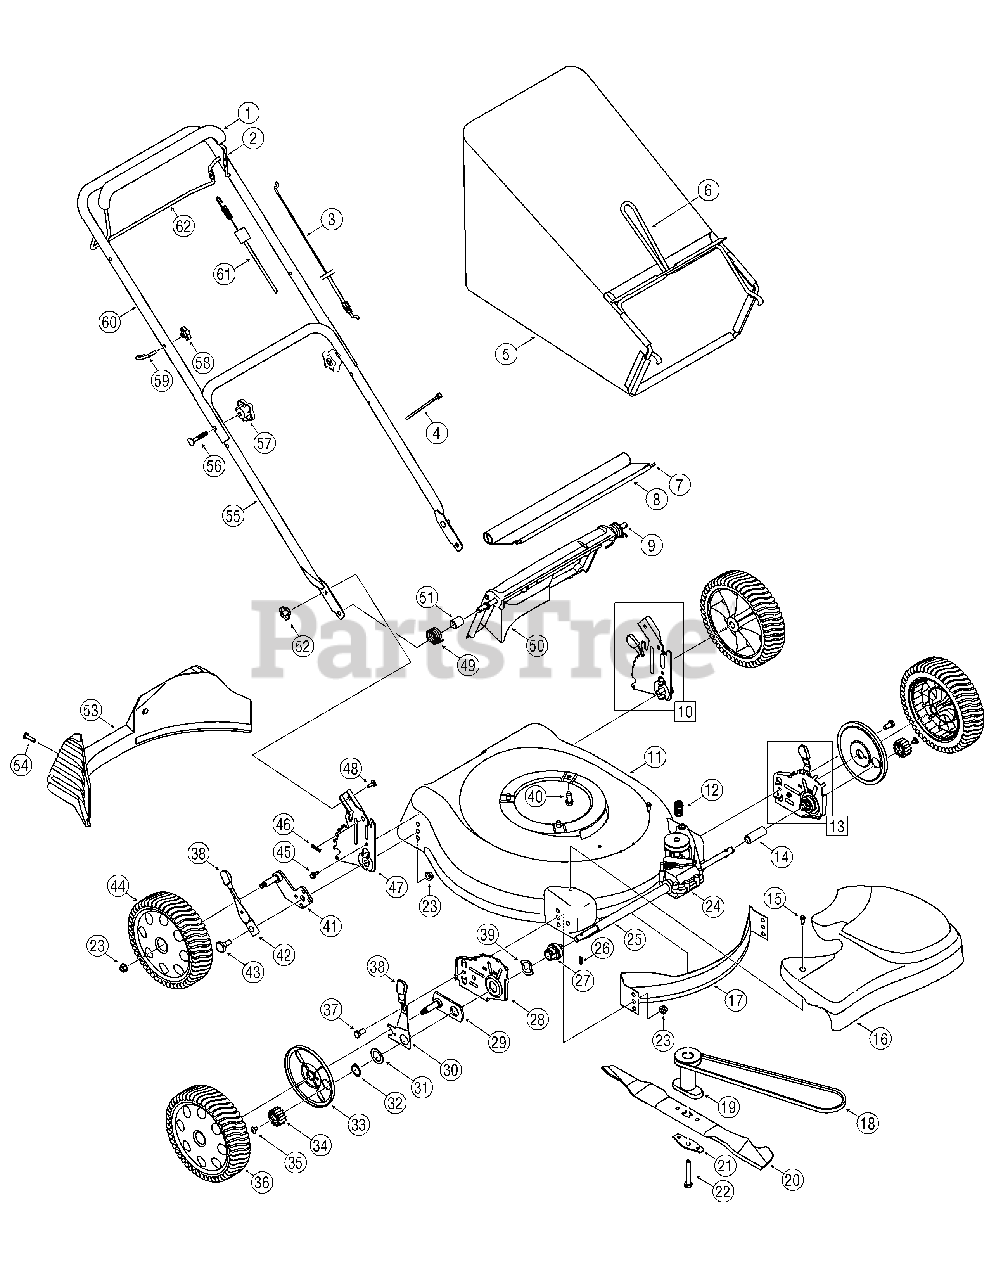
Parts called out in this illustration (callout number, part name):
1	Blade Control Cover
3	Control Cable 40.75"
4	Cable Tie
5	Grass Bag Assembly
7	Trailshield Wire
8	Trailshield
9	Rear Door Pivot Rod
10	Rear Handle Bracket Assy. - LH
10	Rear Handle Bracket Assy. - RH
12	Belt Tension Compression Spring
13	Ht. Adj. Assy. Front - LH
13	Ht. Adj. Assy. Front - RH
14	Sleeve Spacer .52 ID x 1.4
15	Shoulder Screw
16	Front Drive Cover
17	Front Baffle
18	V-Belt
19	Blade Adapter
20	21" Mulching Blade
21	Bell Blade Support
22	Hex Bolt 3/8-24 x 2.5
23	Flange Lock Nut 3/8-16
24	Transmission
25	Sleeve Spacer .52 ID x 8.985
26	Dowel Pin
27	Bearing Assembly
28	Height Adjustment Plate - RH
28	Height Adjustment Plate - LH
29	Pivot Plate Assembly
30	Front Lever - RH
30	Front Lever - LH
31	Washer, 1.5" OD
32	Snap Ring
33	Wheel Dust Cap
34	Gear, 14T - RH
34	Gear, 14T - LH
35	Screw, 1/4-20 x .390
36	Wheel 8 x 2.125 Gear GW S-Wave
37	HH Cap Screw 3/8-16 x 1.00
38	Adjustment Lever Knob
39	Wave Washer
40	TT Sems Screw 3/8-16 x 1
41	Pivot Arm Assembly- RH
41	Pivot Arm Assembly-LH
42	Spring Lever
43	Shoulder Screw
44	Wheel 8 x 2.125 Idle S-Wave
45	TT Screw 1/4-20 x .625
46	Hairpin Clip
47	Handle Bracket- RH
47	Handle Bracket-LH
48	Carriage Bolt
49	Torsion Spring -RH
49	Torsion Spring -LH
50	Rear Discharge Door
51	Spacer
52	Wing Nut, 1/4-20
53	Rear Baffle
54	Screw, 1/4-15 x 1.250
56	Carriage Bolt 5/16-18 x 2
57	Star Knob
58	ERS Handle Knob
61	Control Cable 51" Snap
62	Drive Control
